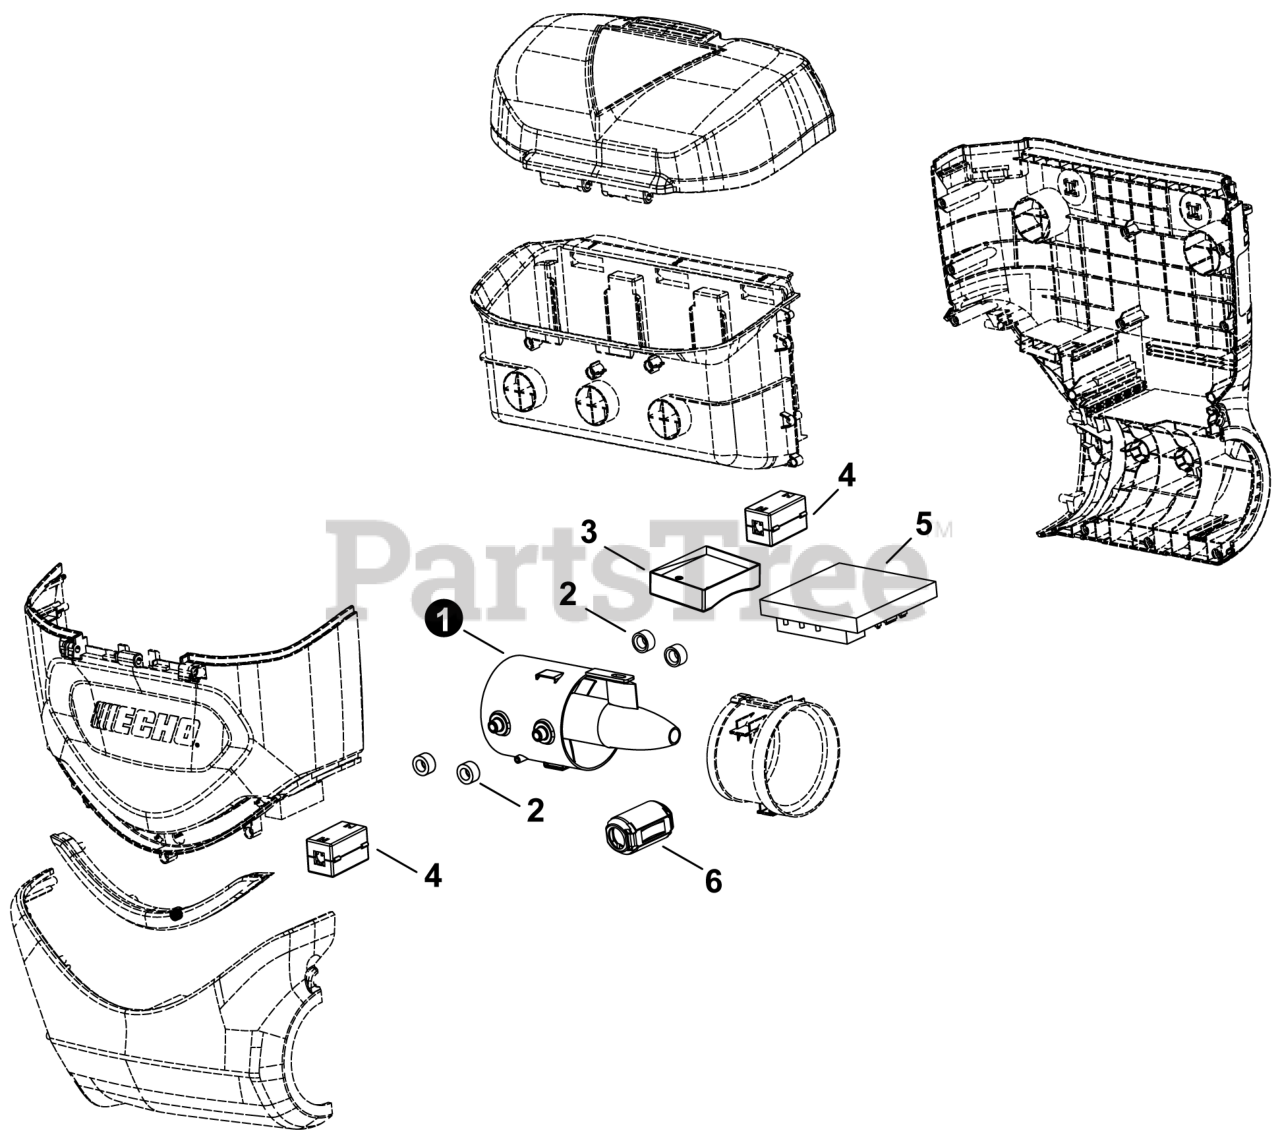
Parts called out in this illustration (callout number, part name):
1	MOTOR ASSY
3	PCBA (PRINTED CIRCUIT BOARD ASSEMBLY)
4	SHIELD, EMC
5	BMCB (BATTERY MANAGEMENT CONTROL BOARD)
6	SHIELD, EMC
